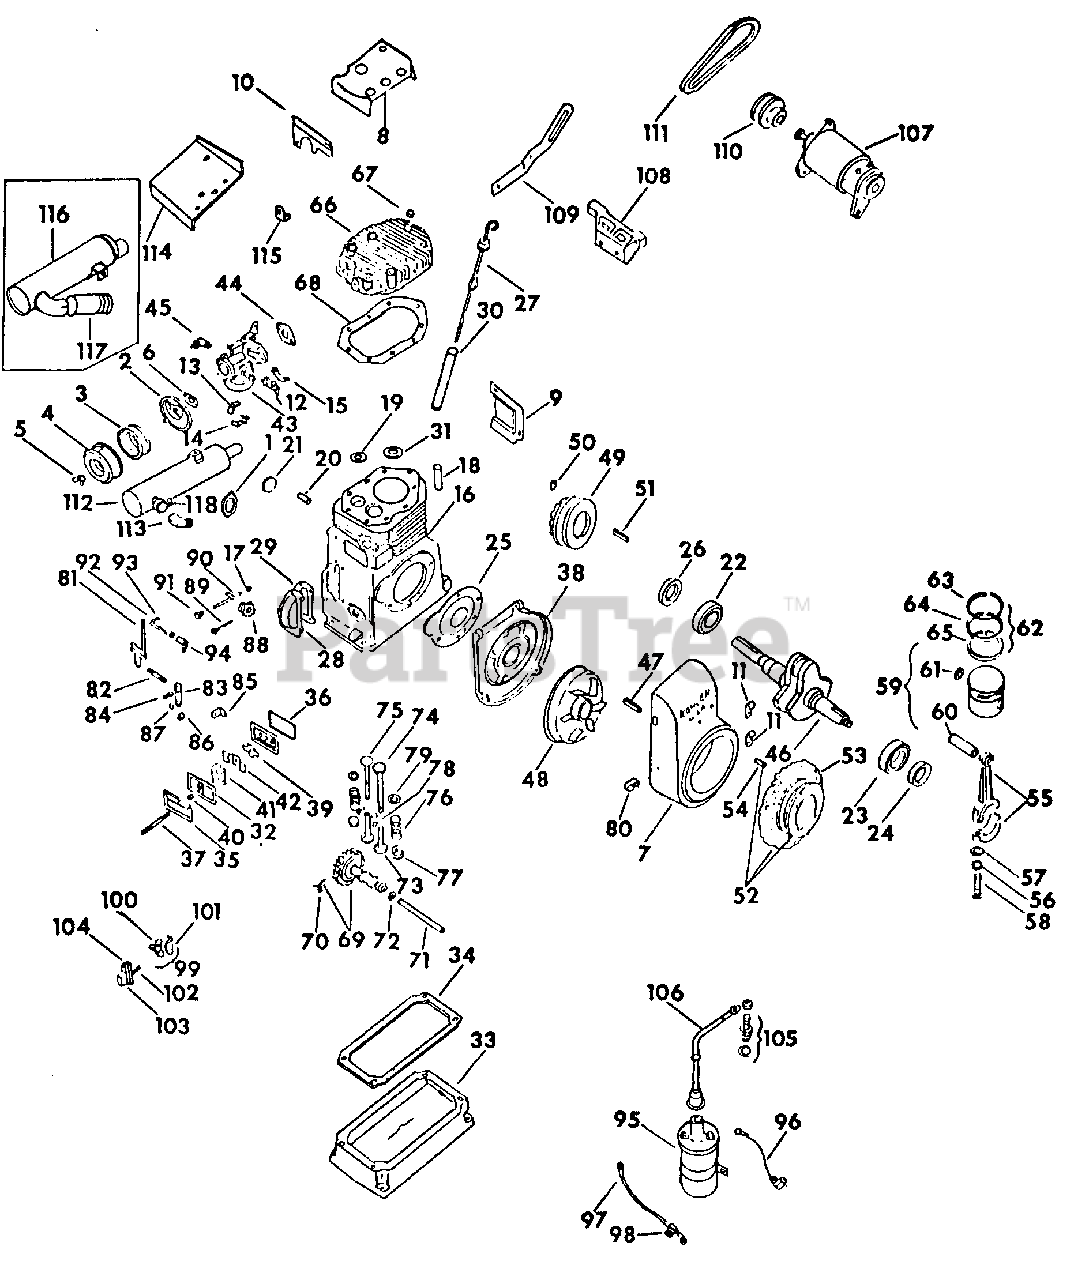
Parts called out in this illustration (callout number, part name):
1	Nut, Exhaust Muffler Elbow Lock
2	Base, Air Cleaner
3	Element, Air Cleaner Filter
4	Cover, Air Cleaner
5	Nut, Air Cleaner Wing
6	Gasket, Air Cleaner
7	Housing, Blower
8	Baffle, Cylinder Head Air
9	Baffle, Cylinder Air
10	Baffle, Housing Side Air
11	Clip, Throttle Cable
12	Clip, Choke Cable
13	Bracket, Throttle Cable
14	Clip, Throttle Cable
15	Bracket, Choke
16	Block, Cylinder
17	Bearing, Needle
18	Guide, Valve
19	Insert, Exhaust Valve
20	Shaft, Governor
21	Plug, 1-1/8 Expansion (Crankcase)
22	Plate Assy, Breather
23	Bearing, Crankcase Ball
24	Seal, Front Plate Oil
25	Gasket, Bearing Plate, .10
26	Seal, Crankcase Rear Oil
28	Cover, Camshaft
29	Gasket, Camshaft Cover
30	Tube, Oil Fill
31	Insert, Intake Valve
32	Gasket, Valve Cover
33	Base, Oil Pan
34	Gasket, Oil Pan Base
35	Cover, Breather
36	Gasket, Breather
37	Stud, Breather Cover
38	Plate, Crankcase Bearing
39	Reed, Breather
40	Seal, Breather
41	Filter, Breather
42	Baffle, Breather
43	Carburetor Assy
44	Gasket, Carburetor
45	Elbow, Carburetor to Fuel Line
47	Key, Crankshaft
48	Flywheel w/Key, IH-532004-R1
49	Pulley w/Clutch Drive Plate, Flywheel
50	Screw, Flywheel Pulley Set
51	Key, 1/4 X 7/8 Sq Parallel
52	Cup Assy, Flywheel Drive
53	Screen, Drive Cup Grass
54	Pin, Flywheel Drive Cup
55	Rod Assy, Connecting, Std
56	Washer, Connecting Rod Lock
57	Washer, Connecting Rod
58	Screw, Connecting Rod
59	Piston Assy, Std
60	Pin, Piston, .005 O/S
61	Retainer, Piston Pin
62	Ring Set, Piston, Std
63	Ring, Top Compression
64	Ring, Center Compression
65	Ring, Oil Control
66	Head, Cylinder
67	Washer, Cylinder Head
68	Gasket, Cylinder Head
69	Camshaft Assy
70	Spring, Camshaft Actuating
71	Pin, Camshaft
72	Shim, Camshaft, .005
73	Tappet Assy, Valve
74	Valve, Intake
75	Valve, Exhaust
76	Spring, Valve
77	Retainer, Valve Spring
78	Keeper, Valve Spring
79	Retainer, Valve Spring Upper
81	Lever, Governor
82	Spring, Governor
83	Bracket, Speed Control
84	Clamp, Control Bracket
85	Bracket, Adjusting Screw
86	Spacer, Adjusting Screw
87	Washer, Adjusting Screw Spacer
88	Gear Assy, Governor
89	Pin, Governor Stop
90	Shaft Assy, Governor Cross
91	Bushing, Cross Shaft
92	Rod, Ball Joint Throttle
93	Retainer, Throttle Rod
94	Joint, 10-32 X 1/4 Ball
95	Coil, Ignition
96	Condenser, Ignition Coil
97	Cable, Breaker
98	Clip, Condenser to Breaker Cable
99	Bracket & Breaker Assy
100	Breaker Contact Set
101	Bracket, Breaker Point
102	Rod, Breaker
103	Cover, Breaker
104	Gasket, Breaker Cover
105	Plug, Spark (Champion)
106	Kit, Hi-Tension Spark Plug Lead
107	Motor Generator
108	Bracket, Motor Generator Mounting
109	Brace, Motor Generator Adjusting
110	Pulley, Motor Generator Drive
111	Belt, Motor Generator Drive
112	Muffler w/Clamp, Exhaust
113	Tube, Exhaust Muffler
114	Baffle, Heat
115	Angle, Hanging Strap
116	Muffler, Exhaust
117	Nipple, 1 X 1-1/4 Pipe
118	Clamp, Muffler
